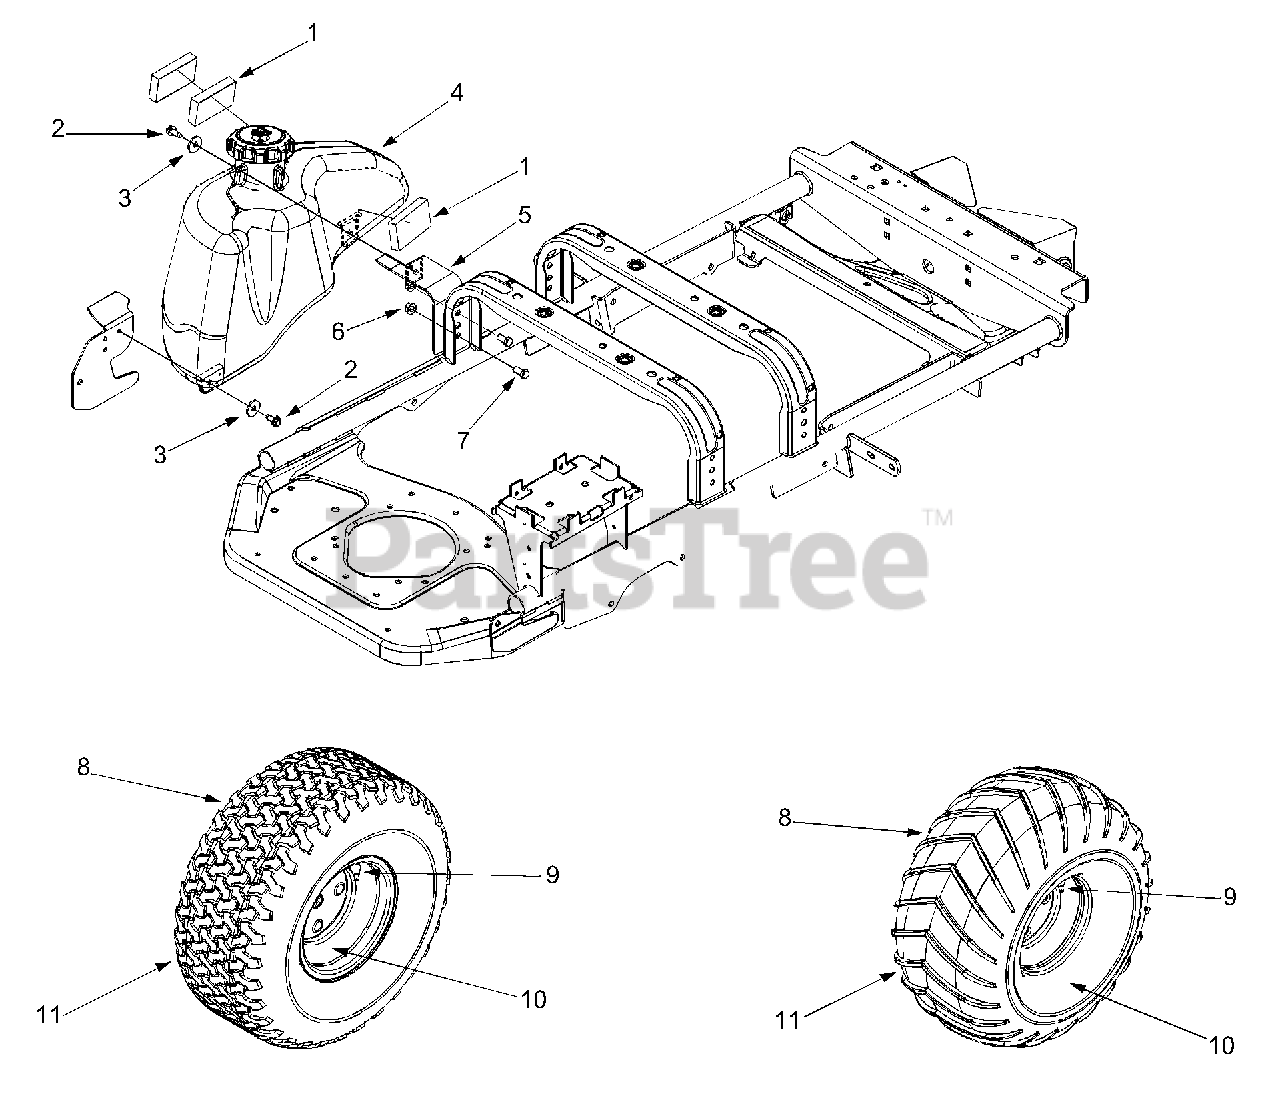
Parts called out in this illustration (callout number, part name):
1	Foam 2.04 x 3.50 x .62
2	Hex Washer Screw 5/16-18 x .75
3	Flat Washer .344 ID x 1.125 OD
4	Tank Assembly 4.0 Gallon
7	Hex Cap Screw 3/8-16 x .75
10	Tubeless Air Valve
